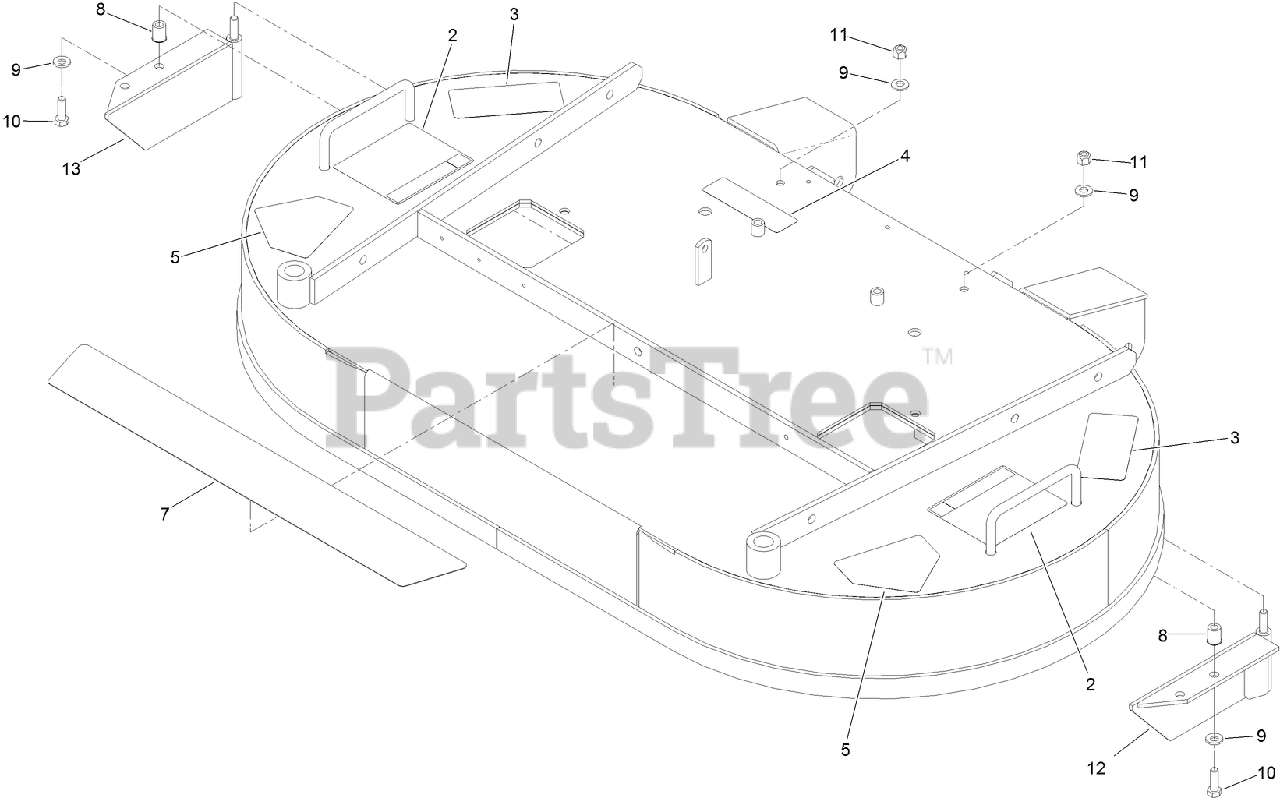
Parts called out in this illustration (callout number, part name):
2	DECAL-HEIGHT ADJUST, CUTTING
3	DECAL-TORQUE, BLADE BOLT
4	DECAL-MISSING, COVER
5	DECAL-DANGER
7	PAD-ANTI SKID
8	NUT-INSERT
9	WASHER-SPRING
10	SCREW-HH
11	NUT-LOCK, NI
12	BAFFLE-LH
13	BAFFLE-RH
